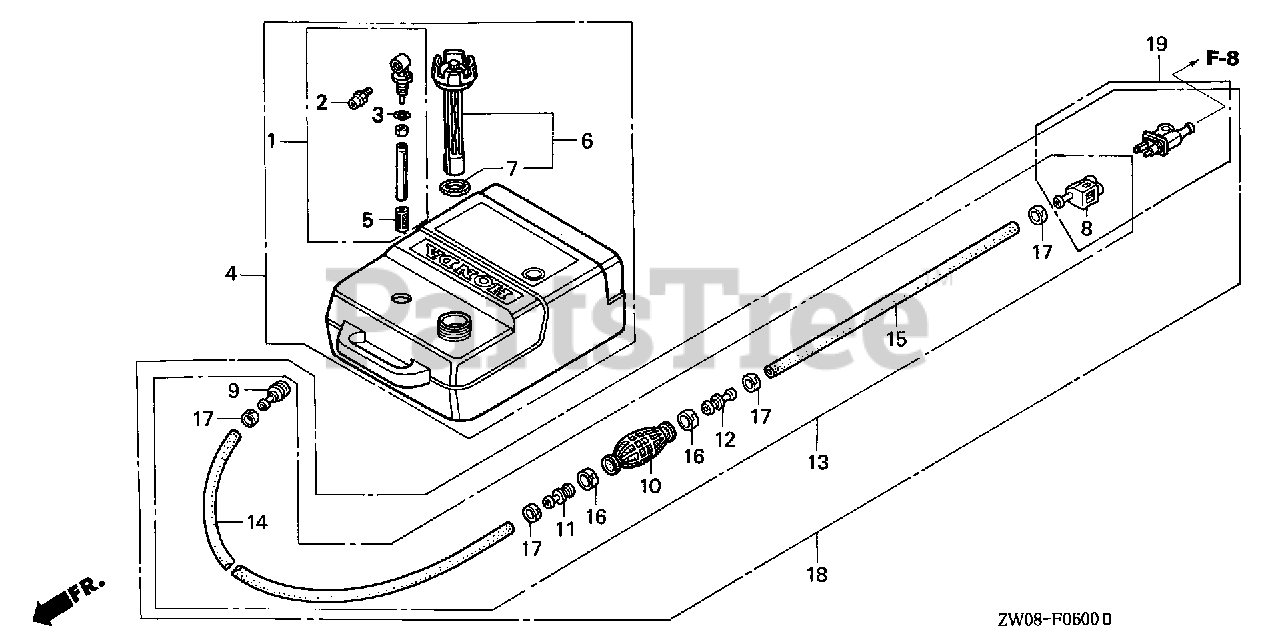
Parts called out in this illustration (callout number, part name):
1	JOINT ASSY., FUEL Use up to Frame SN 1300961.
2	FITTING, QUICK DISCONNECT Use from Frame SN 1205705.
3	O-RING Use from Frame SN 1300962.
4	TANK ASSY., FUEL
5	FILTER, FUEL Use up to Frame SN 1300961.
6	CAP, FUEL FILLER
7	GASKET, FUEL CAP Use up to Frame SN 1300961.
8	CONNECTOR ASSY., FUEL (A)
9	CONNECTOR, FUEL (CONNECTOR TYPE)
10	BULB, PRIMER
11	VALVE, IN.
12	VALVE, OUTLET
13	TUBE ASSY., FUEL
14	TUBE, FUEL LONG (7.3X2000) (CONNECTOR TYPE)
15	TUBE, FUEL SHORT (6.3X500) (CONNECTOR TYPE)
16	BAND, TUBE CLIP (20MM)
17	BAND, TUBE CLIP (12.5MM)
